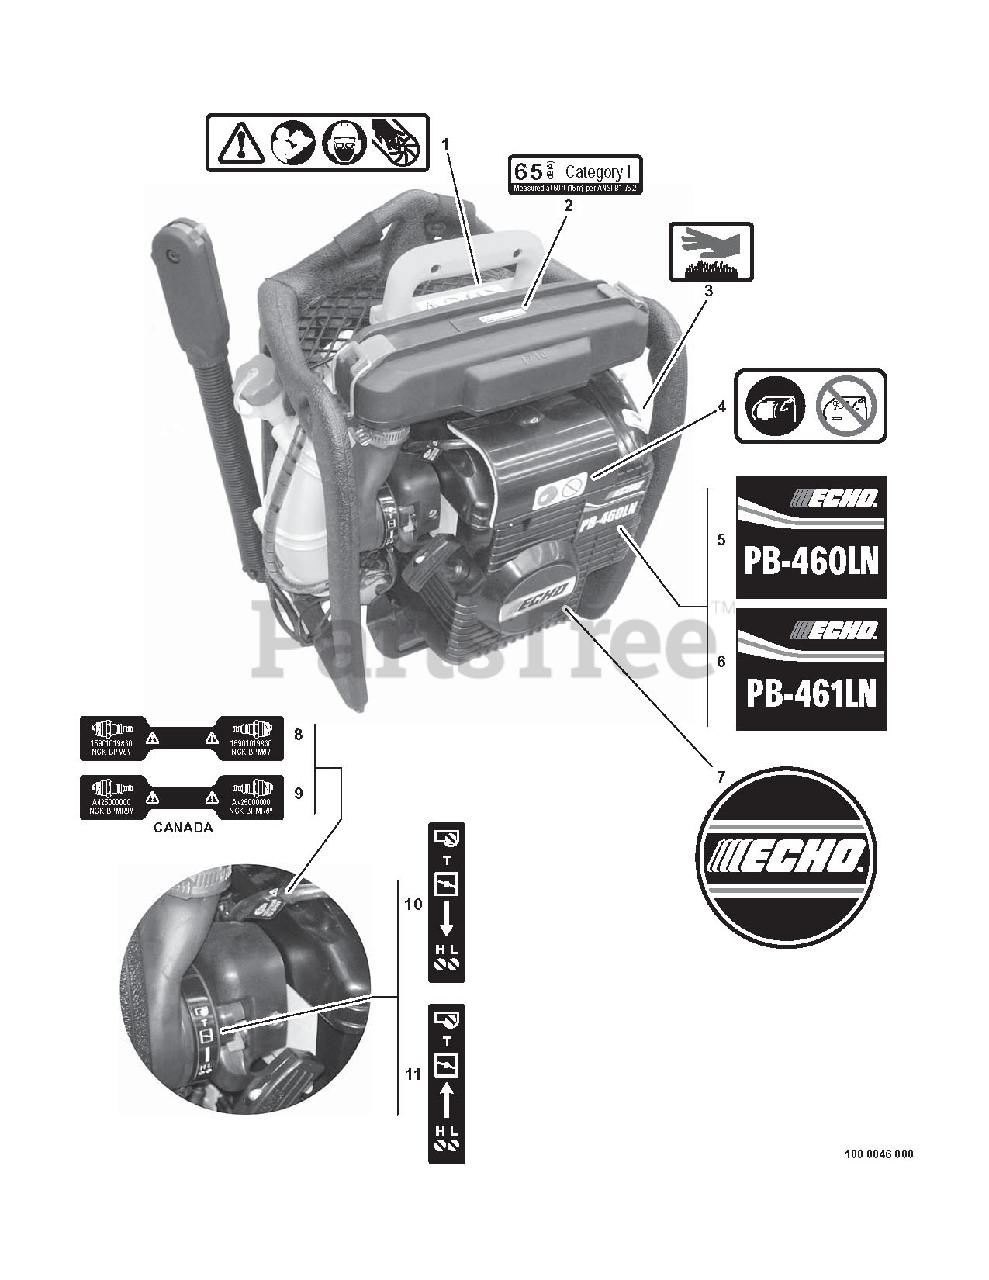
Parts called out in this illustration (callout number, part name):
1	LABEL - CAUTION
2	LABEL - NOISE 65dB(A) CAT I
3	LABEL - HOT SURFACE
4	LABEL - HOT SURFACE
5	LABEL - MODEL PB-460LN
6	LABEL - MODEL PB-461LN
7	LABEL - ECHO
8	LABEL - SPARK PLUG -- BPM-8Y
9	LABEL - SPARK PLUG -- BPMR-8Y
10	LABEL - CHOKE
11	LABEL - CHOKE
